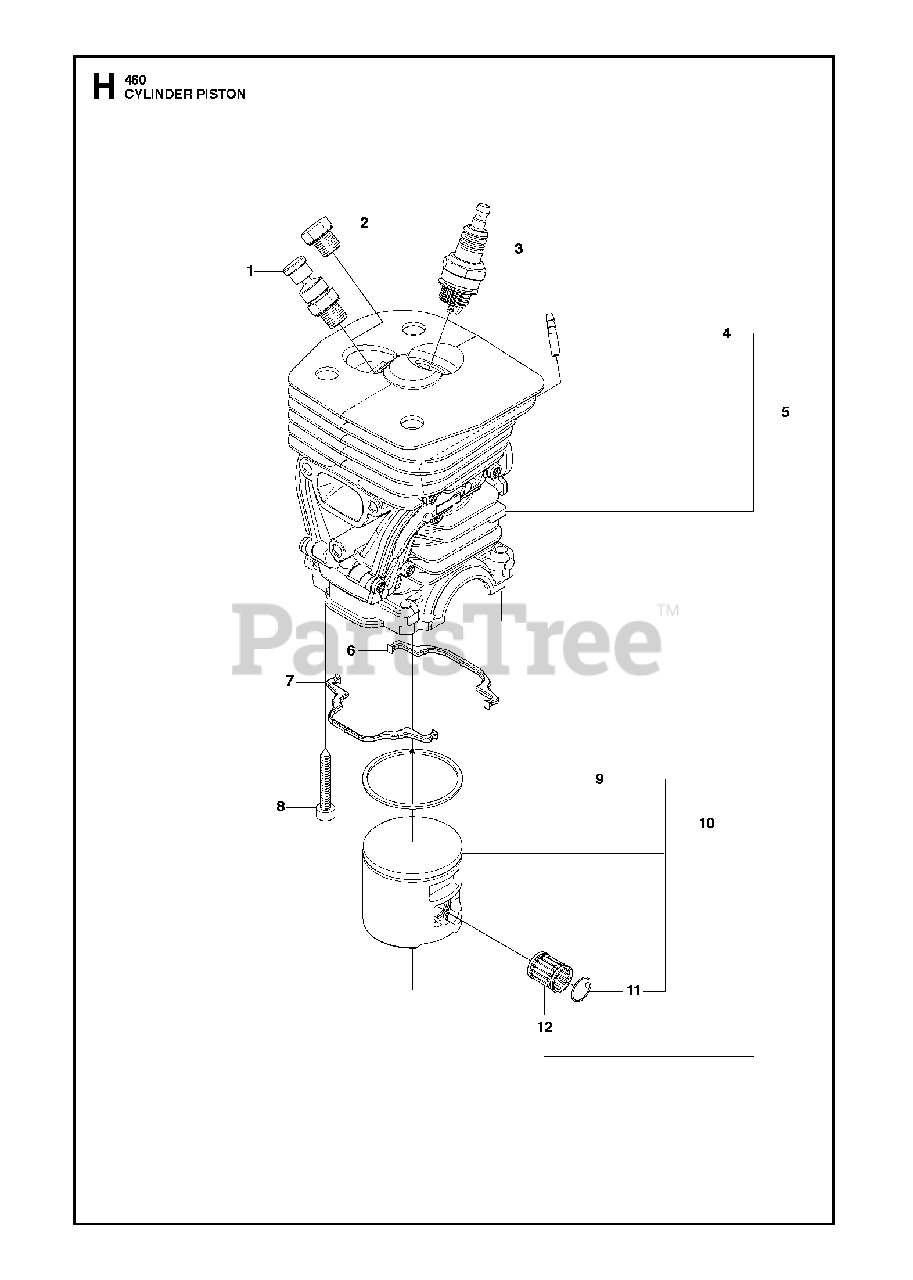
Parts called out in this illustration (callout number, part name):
1	RP VALVE
2	CYLINDER PLUG
3	SPARK PLUG RCJ7Y
4	FITTING
9	PISTON RING
10	PISTON
11	WRIST PIN CLIP
12	SUPPORT BUSHING
